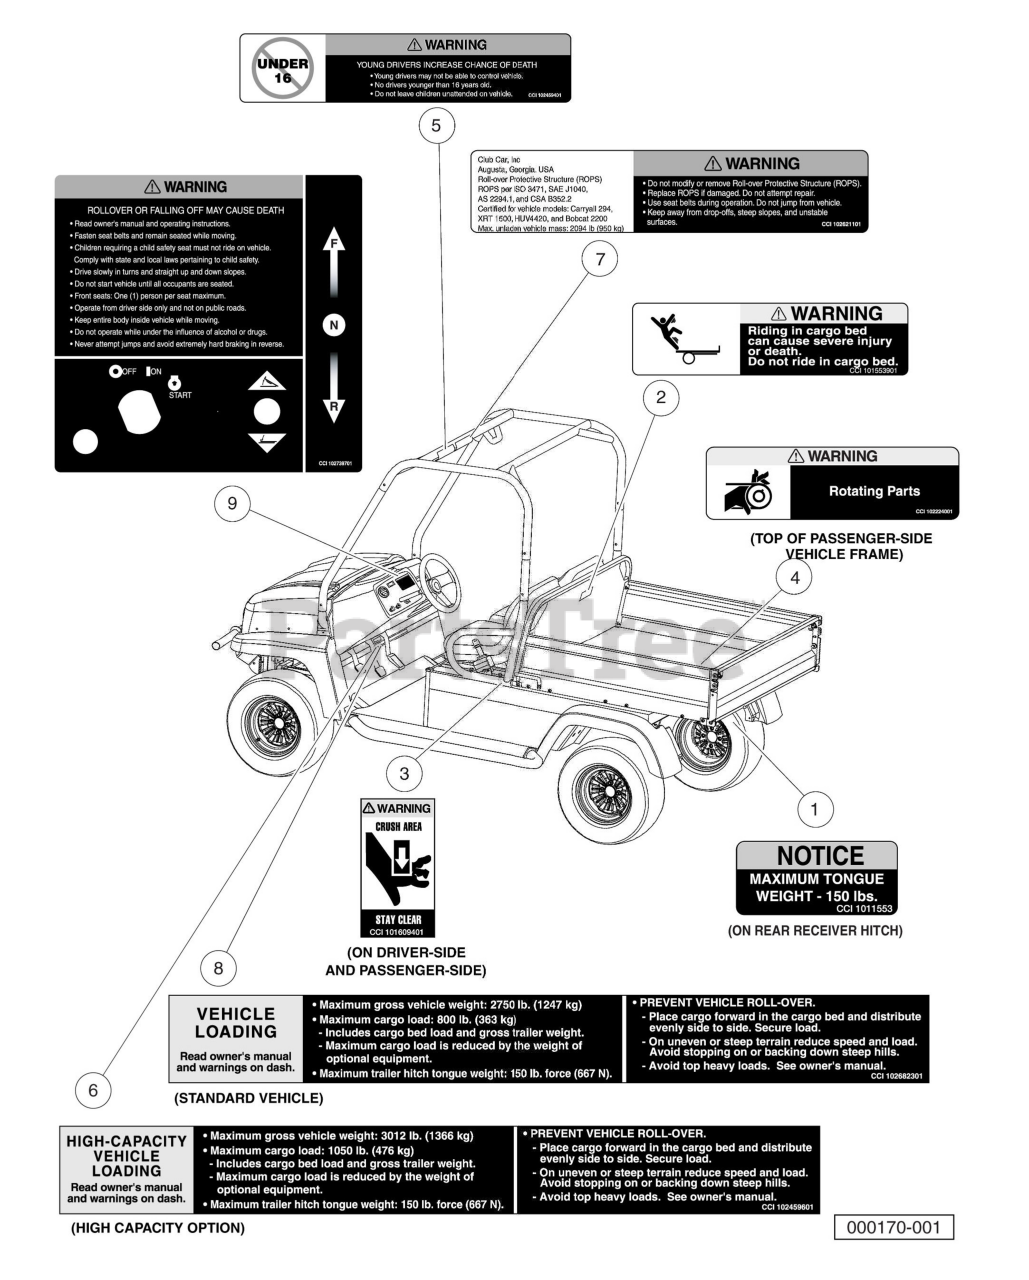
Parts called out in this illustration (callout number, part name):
1	Decal, Trailer Hitch
2	Decal, Bed Load Warning
3	Decal, Crush Area Warning
4	Decal, Rotating Parts Warning
5	Decal, Young Driver Warning
6	Decal, Vehicle Loading, High-Capacity
7	Decal, ROPS Certification/Warning
8	Decal, Vehicle Loading, Standard Capacity
9	Decal, Warning, Gasoline Instrument Panel
